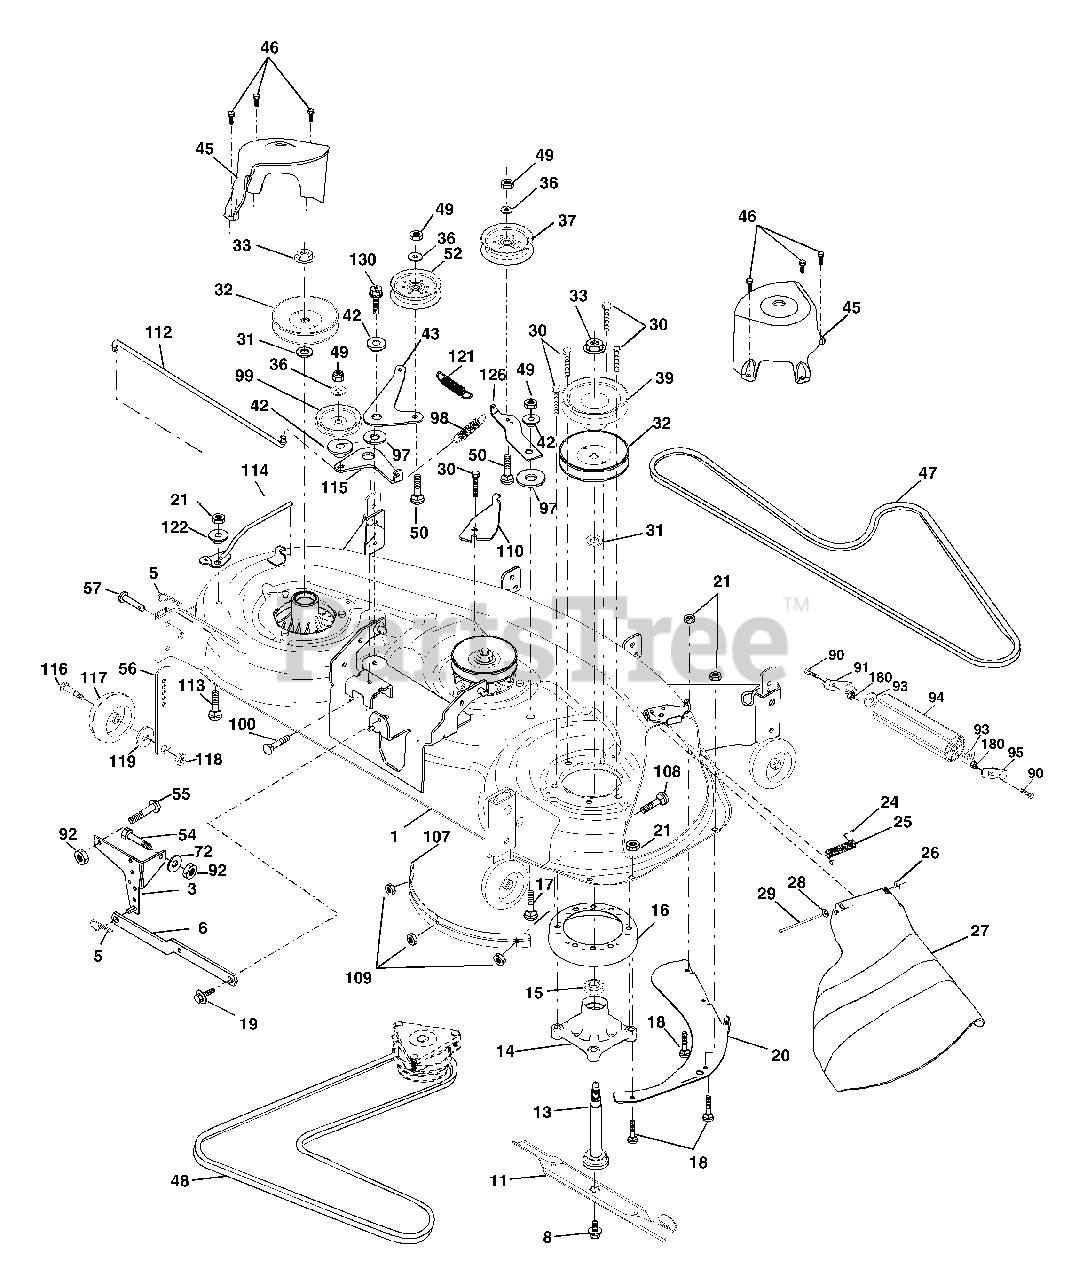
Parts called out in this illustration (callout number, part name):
1	Deck Weldment Mower 48
3	Bracket Asm., Sway Bar
5	Retainer Spring
6	Arm, Suspension, Rear (Sway Bar)
8	Bolt, 7/16 Asm. Blade
11	Blade
13	Shaft Asm. greaseable
14	Housing Mandrel 48"
15	Bearing, Ball, Mandrel
16	Stripper, Mower
17	Bolt Rdhd Sq Neck 3/8-16 x 1.25
18	Bolt, Carriage 5/16-18 x 5/8
19	Bolt, Hex Head, Shoulder 5/16-18
20	Baffle, Vortex Mower
21	Nut, Crownlock 5/16-18 UNC
24	Cap, Sleeve
25	Spring, Torsion
27	Shield, Deflector Mower
28	Washer 11/32 x 5/8 x 16 Ga.
29	Rod, Hinge
30	Screw, Thdroll, Washer Head
31	Washer, Spacer Mower Vented
32	Pulley, Mandrel
33	Nut, Flg. Top Lock Cntr. 9/16
36	Washer 13/32 x 13/16 x 16 Ga.
37	Pulley, Idler, Flat
39	Pulley, Idler, Driven
42	Spacer, Retainer
43	Arm, Idler Secondary
45	Cover, Mandrel Deck
46	Screw, Thdroll. 1/4-20 x 5/8
47	V-Belt, Mower, Secondary
48	V-Belt, Mower, Primary
49	Nut, Crownlock 3/8-16 UNC
50	Bolt, Carriage 3/8-16 x 1-1/2 Gr. 5
52	Pulley Idler Flat 46 Pri. Drive
54	Bolt Fin Hex 3/8-16 x 1
55	Bolt Rdhd Sqnk 3/8-16 x 1
56	Bar Pnt Adjusting Wheel Gauge
57	Pin Head Rivet
72	Washer 13/32 x 13/16 x 12
90	Bolt, Fin, Hex 5/16-18 x 1.0
91	Bracket, Asm Noseroller, LH 48
92	Nut Lock Hex w/Ins 3/8-16
93	Washer 17/32 x 7/8 x 16 Ga.
94	Roller, Nose 48"
95	Bracket, Asm Noseroller RH 48
97	Washer Hardened
98	Spring Primary Drive
99	Pulley Idler "V"
100	Bolt RDHD Sqnk 3/8-16 Unc x 2
107	Baffle Vac Edge Mower
108	Bolt Carr.
109	Nut Crownlock 1/4-20
110	Arm Spring Secondary
112	Link Tension Relief Lever
113	Bolt Carr. 5/16-18 x 1
114	Tension Asm Relief Lever
115	Arm Spring Tension Relief
116	Bolt, Shoulder
117	Gauge Wheel
118	Nut, Centerlock 3/8-16 UNC
119	Washer 3/8 x 7/8 x 14 Ga.
121	Spring Secondary Drive
122	Bushing Pivot Tension Relief
126	Arm, Idler, Primary Deck
130	Screw 3/8-16 x 1.0
180	Nut 5/16-18
